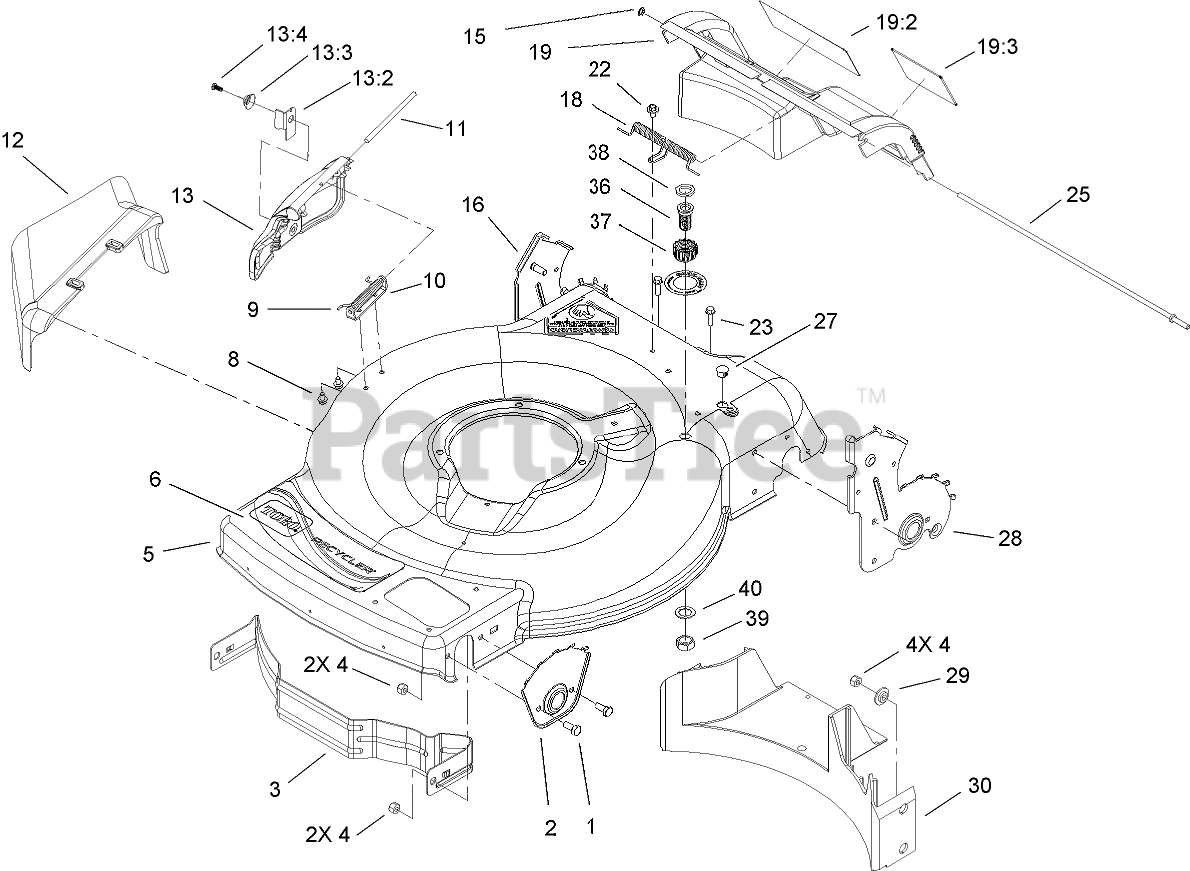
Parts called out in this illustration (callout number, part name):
1	SCREW-HH
2	Plate-HOC, Front
3	Baffle-Front
4	NUT-LOCK, NI
5	HOUSING ASM
6	DECAL-RECYCLER (RWD)
8	SCREW-HWH
9	SPRING-TORSION
10	BRACKET-COVER
11	ROD-COVER
12	CHUTE-DISCHARGE, SIDE
13	DISCHARGE DOOR ASM
13:2	LATCH-DOOR
13:3	CAP-DOOR
13:4	SCREW-PLASTITE
15	NUT-PUSH
16	8 INCH RH HOC PLATE ASM
18	Spring-Door, Rear
19	REAR DOOR ASM
19:2	DECAL-WARNING
19:3	DECAL-WARNING
22	SCREW AND WASHER ASM
23	SCREW-HWH
25	Rod-Pivot, Rear Door
27	Plug-Dome
28	8 INCH LH HOC PLATE ASM
29	Washer-Stepped
30	Baffle-Rear
36	PORT-WASHOUT
37	COUPLING-HOSE, WASHOUT PORT
38	WASHER-SEAL, WASHOUT PORT
39	NUT-JAM
40	WASHER-TOOTH, INTERNAL
